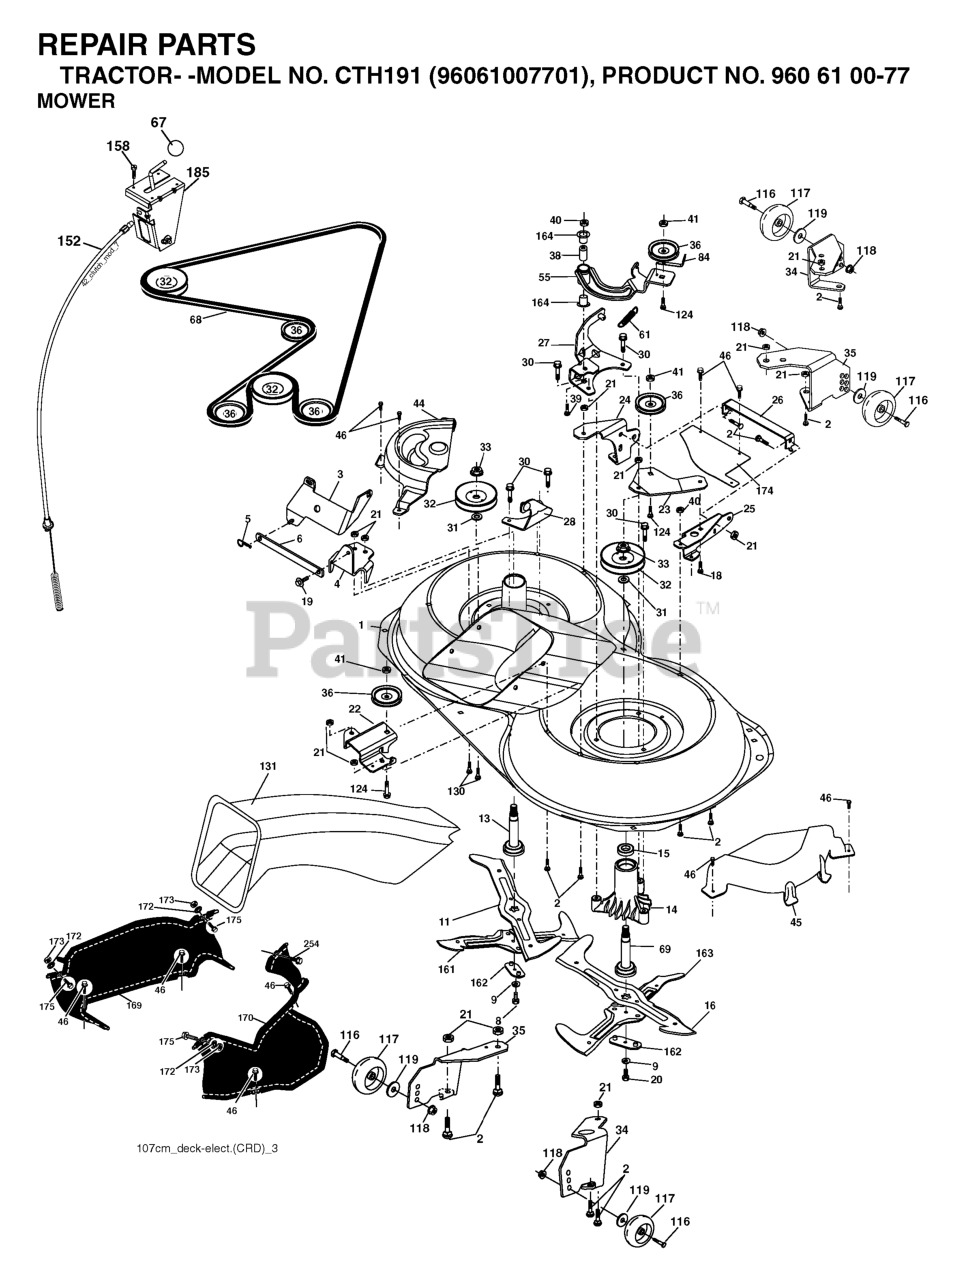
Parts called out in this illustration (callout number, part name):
1	Housing Asm. Mower 107 CRD
2	RP BOLT 5/16-18 X3/4 ZN/YEL GR
5	RETAINER-SPRNG RB
6	BAR.SWAY.92.CRD
8	BOLT.3/8-24X1.25 GR8
9	LOCKWASHER
11	BLADE.3N1.LH.CRD
13	SHAFT ASM VENT
14	HOUSING.MANDREL.VENTED (MACHD)
16	BLADE.3N1.RH.CRD
19	BOLT SHD 5/16-18
20	BOLT.3/8-24X1.25GR8. LHTHRD
21	LOCKNUT
22	BRACKET.IDLER.RR.107.CRD
25	BRACKET RF
26	SUPPORT
28	BRACKET
30	SCREW, WASHER HEAD
31	WASHER.SPACER.MANDREL
33	NUT.FLANGE.LOCK.TOP
34	BRACKET
35	BRACKET
36	PULLEY.IDLER.4.25
41	NUT LOCK FLG 3/8-16 UNC
45	COVER.MANDREL.RH.CRD
46	SCREW.1/4-20X5/8
55	ARM.IDLER.107.CRD
67	KNOB T (3/8 HOLE)
68	HEX-BELT 107 MOWER
69	SHAFT.ASM.W/LWR.BRG.RH.THREAD
84	KEEPER, BELT IDLER
116	SHOULDER BOLT
117	RP WHEEL. GUAGE RALLY
118	LOCKNUT
119	WASHER.5/16.FLAT.STE.STD.
124	BOLT.3/8-16X1.50
130	BOLT.CARR.SQNK.5/16-18UNC.X3/4
131	CHUTE BAGGER
158	SCREW
163	BLADE.CROSS.RH.CRD.107
164	BRNG T
172	PUSH.NUT.ROUND.3/8.DIAM
173	NUT
174	PLATE
175	BOLT D
185	HEAD ASM. CABLE CLUTCH
254	SCREW 3/8-16X1
